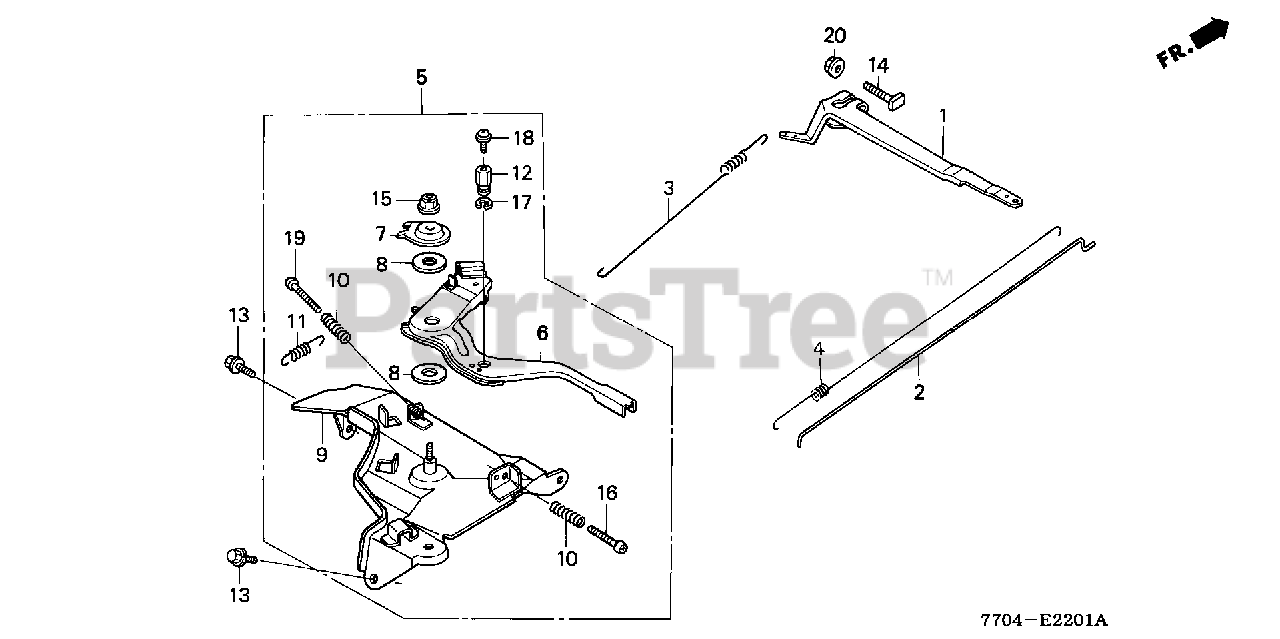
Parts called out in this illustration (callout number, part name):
1	ARM, GOVERNOR
2	ROD, GOVERNOR
3	SPRING, GOVERNOR (L=145.0MM) (WIRE DIAMETER 1.0MM)
4	SPRING, THROTTLE RETURN
5	CONTROL ASSY.
6	LEVER, CONTROL
7	WASHER, CONTROL LEVER
8	SPACER, CONTROL LEVER
9	BASE, CONTROL
10	SPRING, CONTROL ADJUSTING
11	SPRING, CABLE RETURN
12	HOLDER, WIRE
13	BOLT, FLANGE (6X12) (CT200)
14	BOLT, GOVERNOR ARM
15	NUT, SELF-LOCK (6MM)
16	SCREW, LOCK PAN (5X35)
17	CIRCLIP (5MM)
18	SCREW, PAN (4X6)
19	SCREW, PAN (5X28)
20	NUT, FLANGE (6MM)
